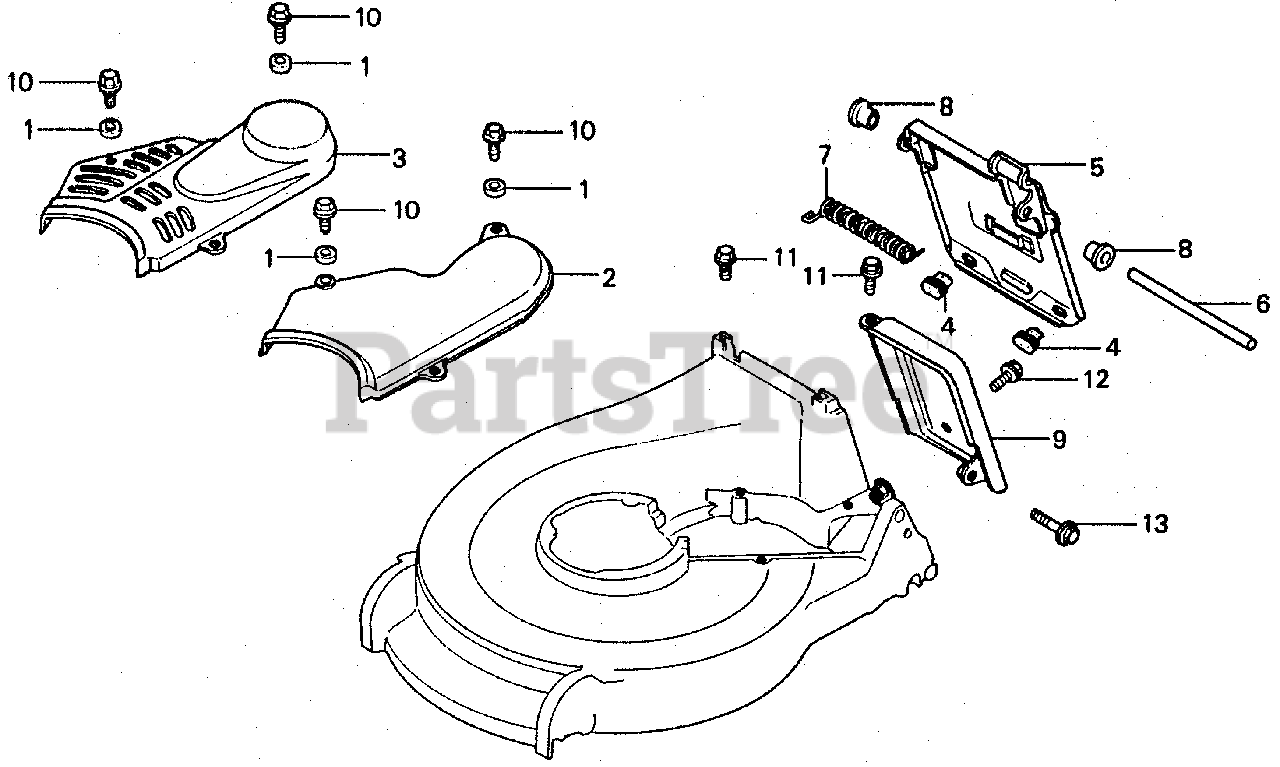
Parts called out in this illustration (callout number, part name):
1	COLLAR, FAN
2	COVER, BELT
4	STOPPER, DISCHARGE GUARD
5	GUARD, DISCHARGE
6	SHAFT, DISCHARGE GUARD
7	SPRING, GUARD RETURN (NOT AVAILABLE)
8	BUSH, DISCHARGE GUARD
9	PANEL, BAG OPEN *NH2M* (METALLIC SILVER)
10	BOLT, FLANGE (6X14)
11	BOLT, FLANGE (6X20) (CT200)
12	BOLT, FLANGE (6X12)
13	BOLT, FLANGE (6X25)
